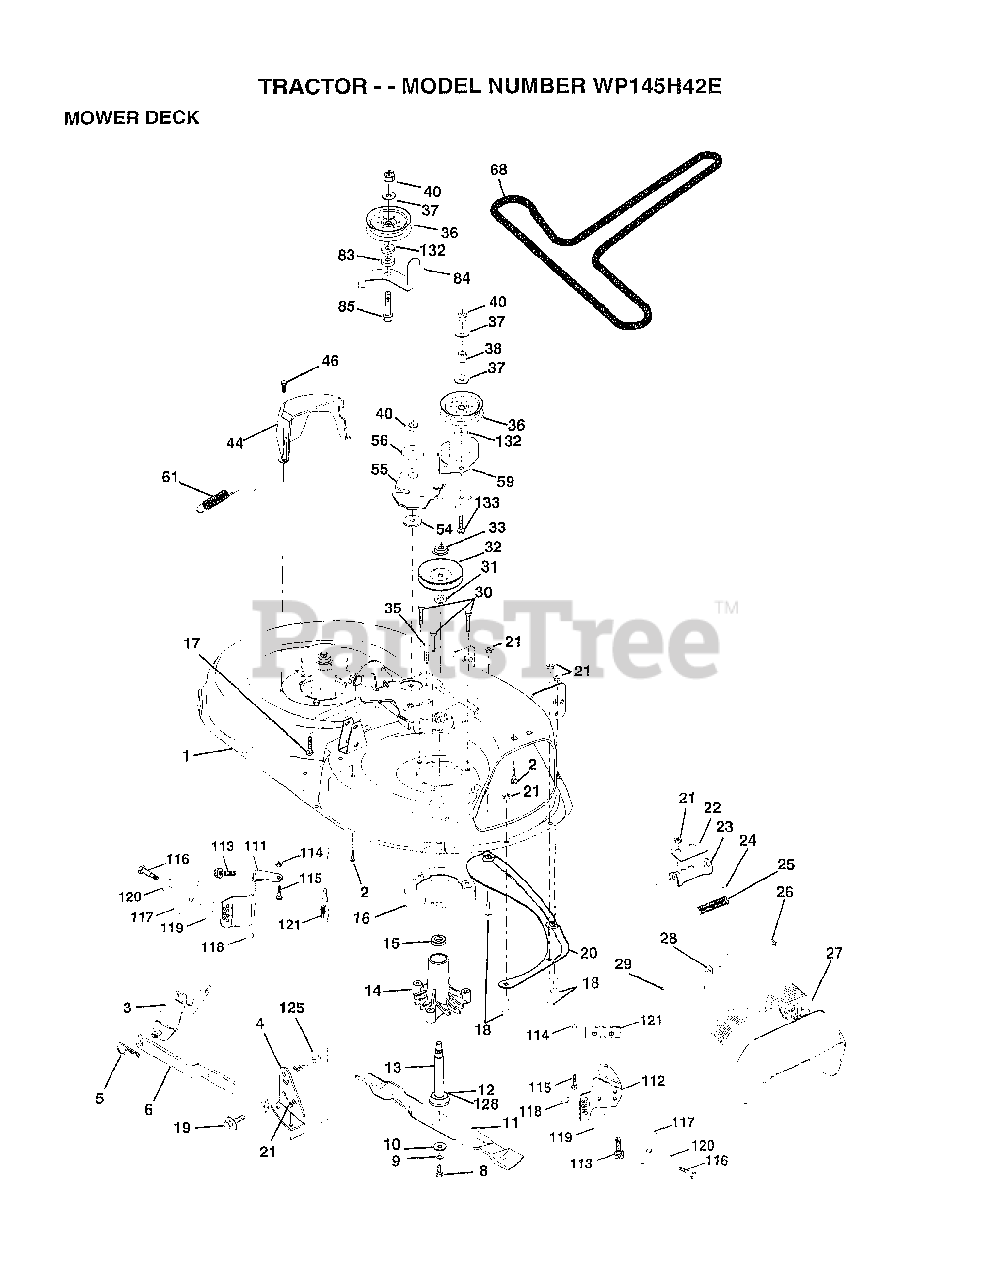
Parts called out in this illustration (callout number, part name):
1	DECK.WELD.42.
2	BOLT
3	BRKT ASM SWAY BAR
4	BRKT DECK SW BAR
8	BLADE BOLT
10	WASHER.HARD.BLADE
11	"BLADE.42"" HIPERF"
12	BEARING.BALL
14	HSG ASM MANDREL
15	BEARING
16	STRIPPER RND MWR
17	BOLT CARRIAGE
18	BOLT
19	BOLT SHD 5/16-18
20	BAFFLE VORTEX 42
22	STIFFENER BRKT
23	DEFLECTOR BRKT
25	SPRING TORSION
27	DEFLECTOR.SHIELD
28	WASHER
29	HINGE ROD
30	"SCREW-THD ROLL,WA"
31	WASHER
32	PULLEY.MANDREL.42
35	XMAS TREE FASTNER
36	FLAT IDLER PULLEY
37	WASHER
44	GUARD MAND LH BLK
46	SCREW.1/4-20X5/8
54	HARDENED WASHER
56	SPACER RETAINER
59	GUARD IDLER TUV
61	SPRING.EXTENSION
68	BELT.V.T-PATH
83	WASHER
84	"KEEPER-BELT,FIXED"
85	BOLT RDHD 3/8-16
111	BRACKET.GWHL.LH.
112	BRACKET.GWHL.RH.
113	SCREW
116	BOLT M
117	WHEEL.GAGE.BLK.PL
118	LOCKNUT
119	WASHER
120	WASHER
121	BRACKET.EXTRD.GWL
128	WASHER.FELT.
132	WASHER GT
133	BOLT
